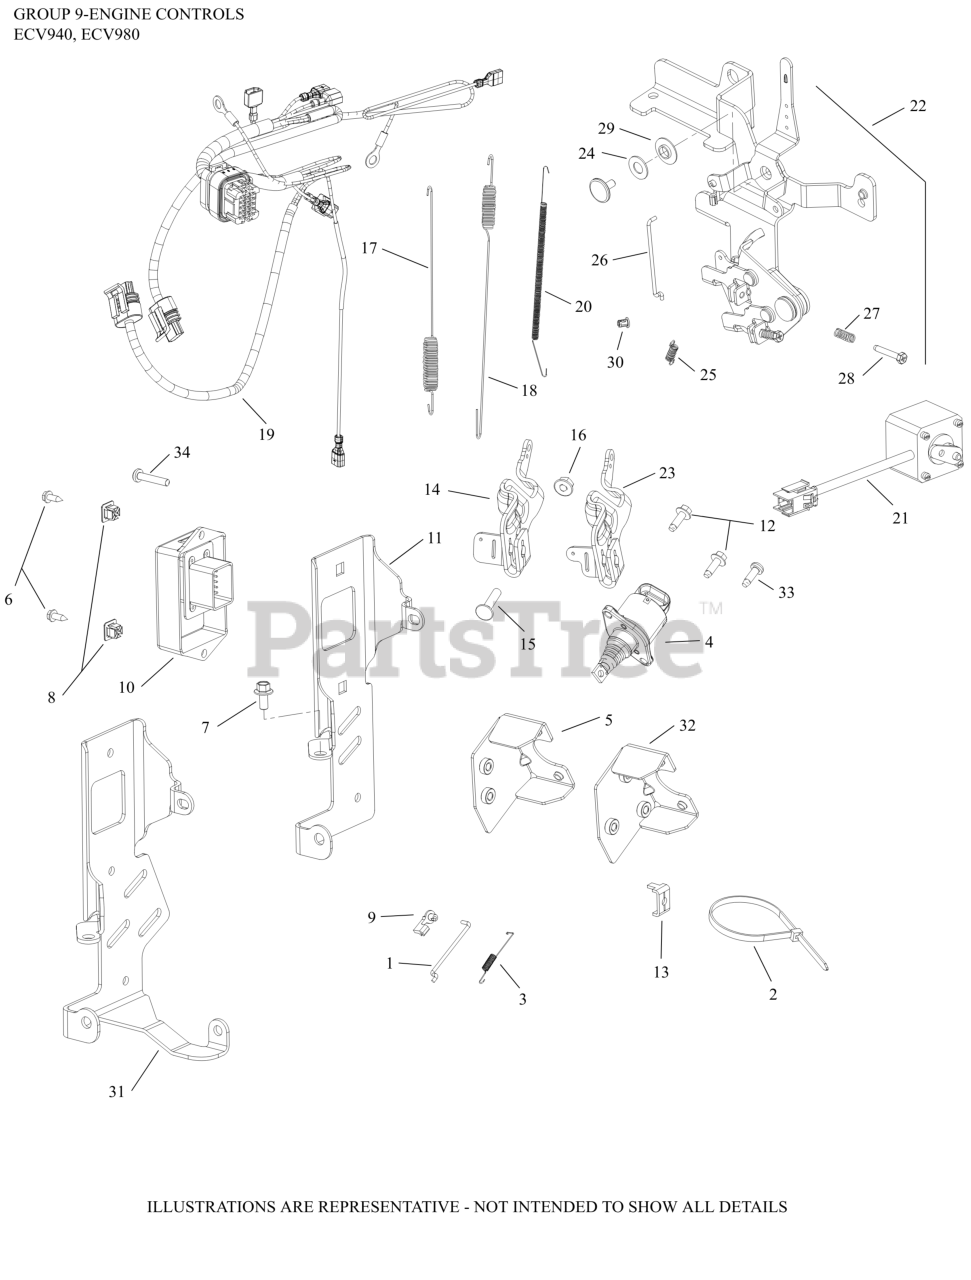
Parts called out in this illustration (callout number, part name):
1	INKAGE, THROTTLE EFI, VERTICAL
7	SCREW, FLG M6X1.0X12
9	BUSHING, THROTTLE LINKAGE
12	SCREW, THREAD FORMING
13	CLAMP, CABLE-(#2523753S)
15	BOLT, RD HD SQ NECK M6X1.0X25
16	NUT, FLG M6X1.0
17	SPRING, GOV (IDLE 1400-1625)
17	SPRING, GOVERNOR
20	SPRING, LINKAGE
22	CONTROL ASSY SPEED (VERTICAL) EFI
23	KIT, GOVERNOR LEVER
24	WASHER, FLAT 9 MM
25	SPRING, RETURN
26	LINKAGE, THROTTLE LEVER
27	SPRING, SPEED CONTROL (SHORT)
28	SCREW, PHL THD FRM M4X0.7X25
29	WASHER, NYLON SHOULDER
